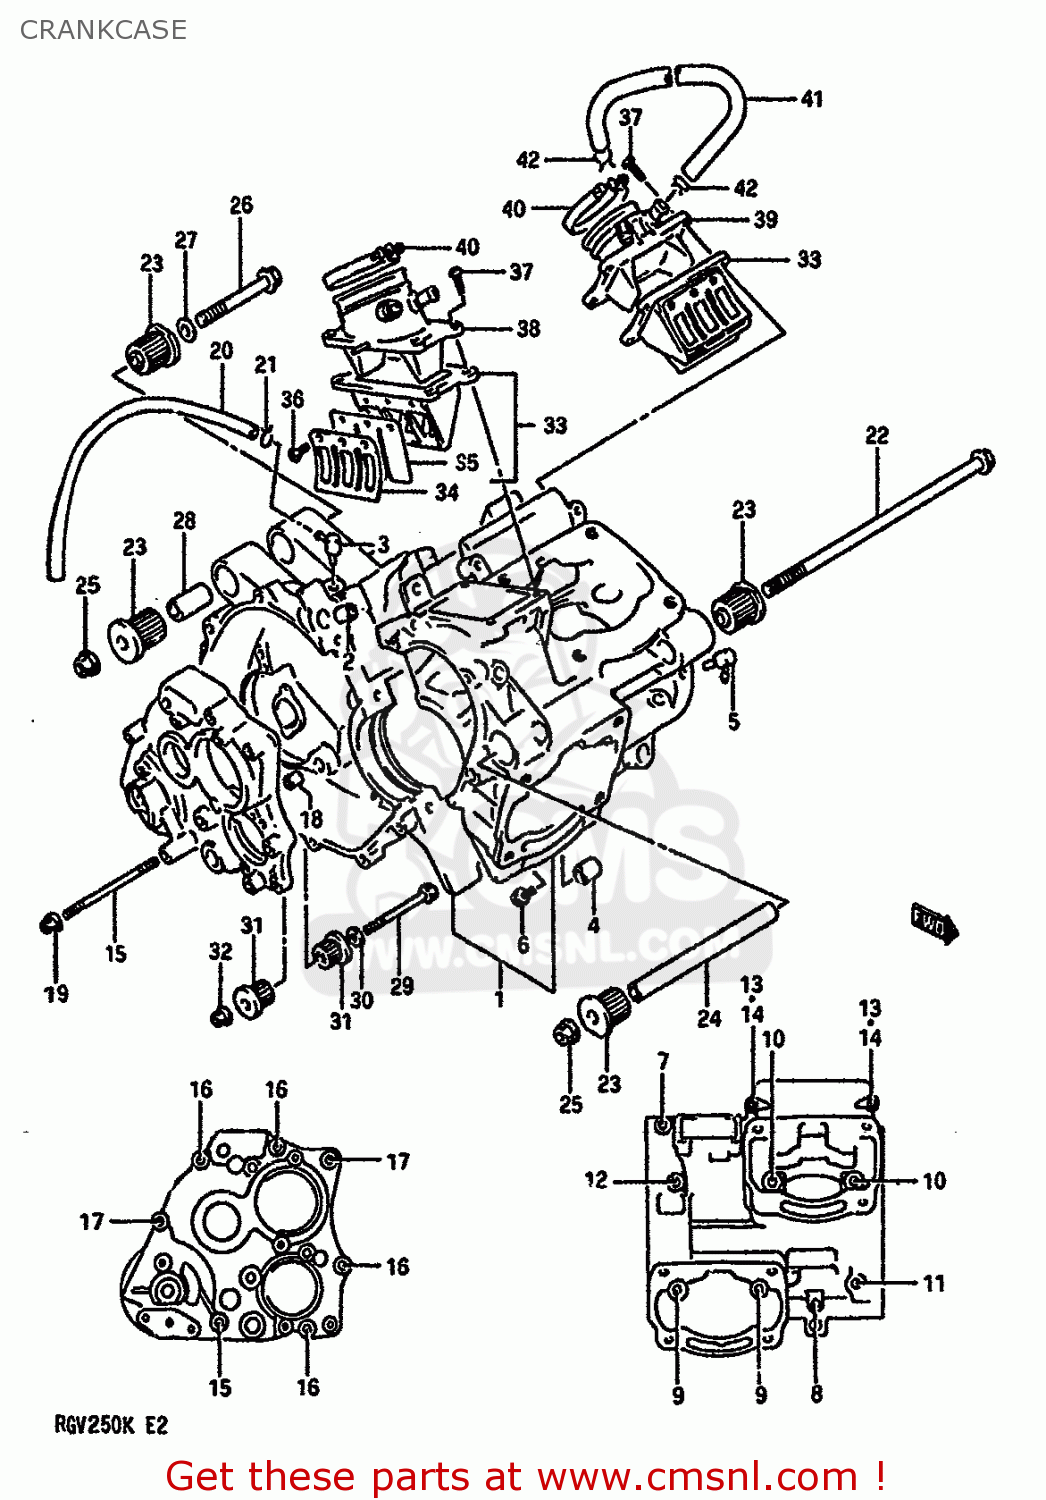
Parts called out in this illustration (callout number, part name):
1	CRANKCASE SET
2	PIN(10.4X13X22)
3	UNION,BREATHER HOSE
4	SPACER(12X16X20)
5	VALVE,OIL HOSE CHECK
6	BOLT
7	BOLT
8	BOLT ,6X50
9	BOLT, FRONT RH
10	BOLT
11	BOLT, REAR RH
12	BOLT 8X110
13	STUD
14	NUT
15	BOLT,STUD
16	STUD 6X30
17	STUD BOLT
18	PIN(8.4X11X18)
19	NUT
20	HOSE
21	CLIP
22	BOLT(10X225)
23	BUSH (10X26.4X33)
24	SPACER
25	NUT
26	BOLT(10X125)
27	WASHER
28	SPACER,10.2X16
29	BOLT(8X70)
30	WASHER
31	BUSH (8.4X16X37.6)
32	NUT
33	VALVE ASSY,REED
34	STOPPER,REED VALVE
35	VALVE,REED
36	SCREW
37	SCREW
38	PIPE,INTAKE,R
39	PIPE,INTAKE,L
40	CLAMP
41	HOSE 8X12.5
42	CLIP
